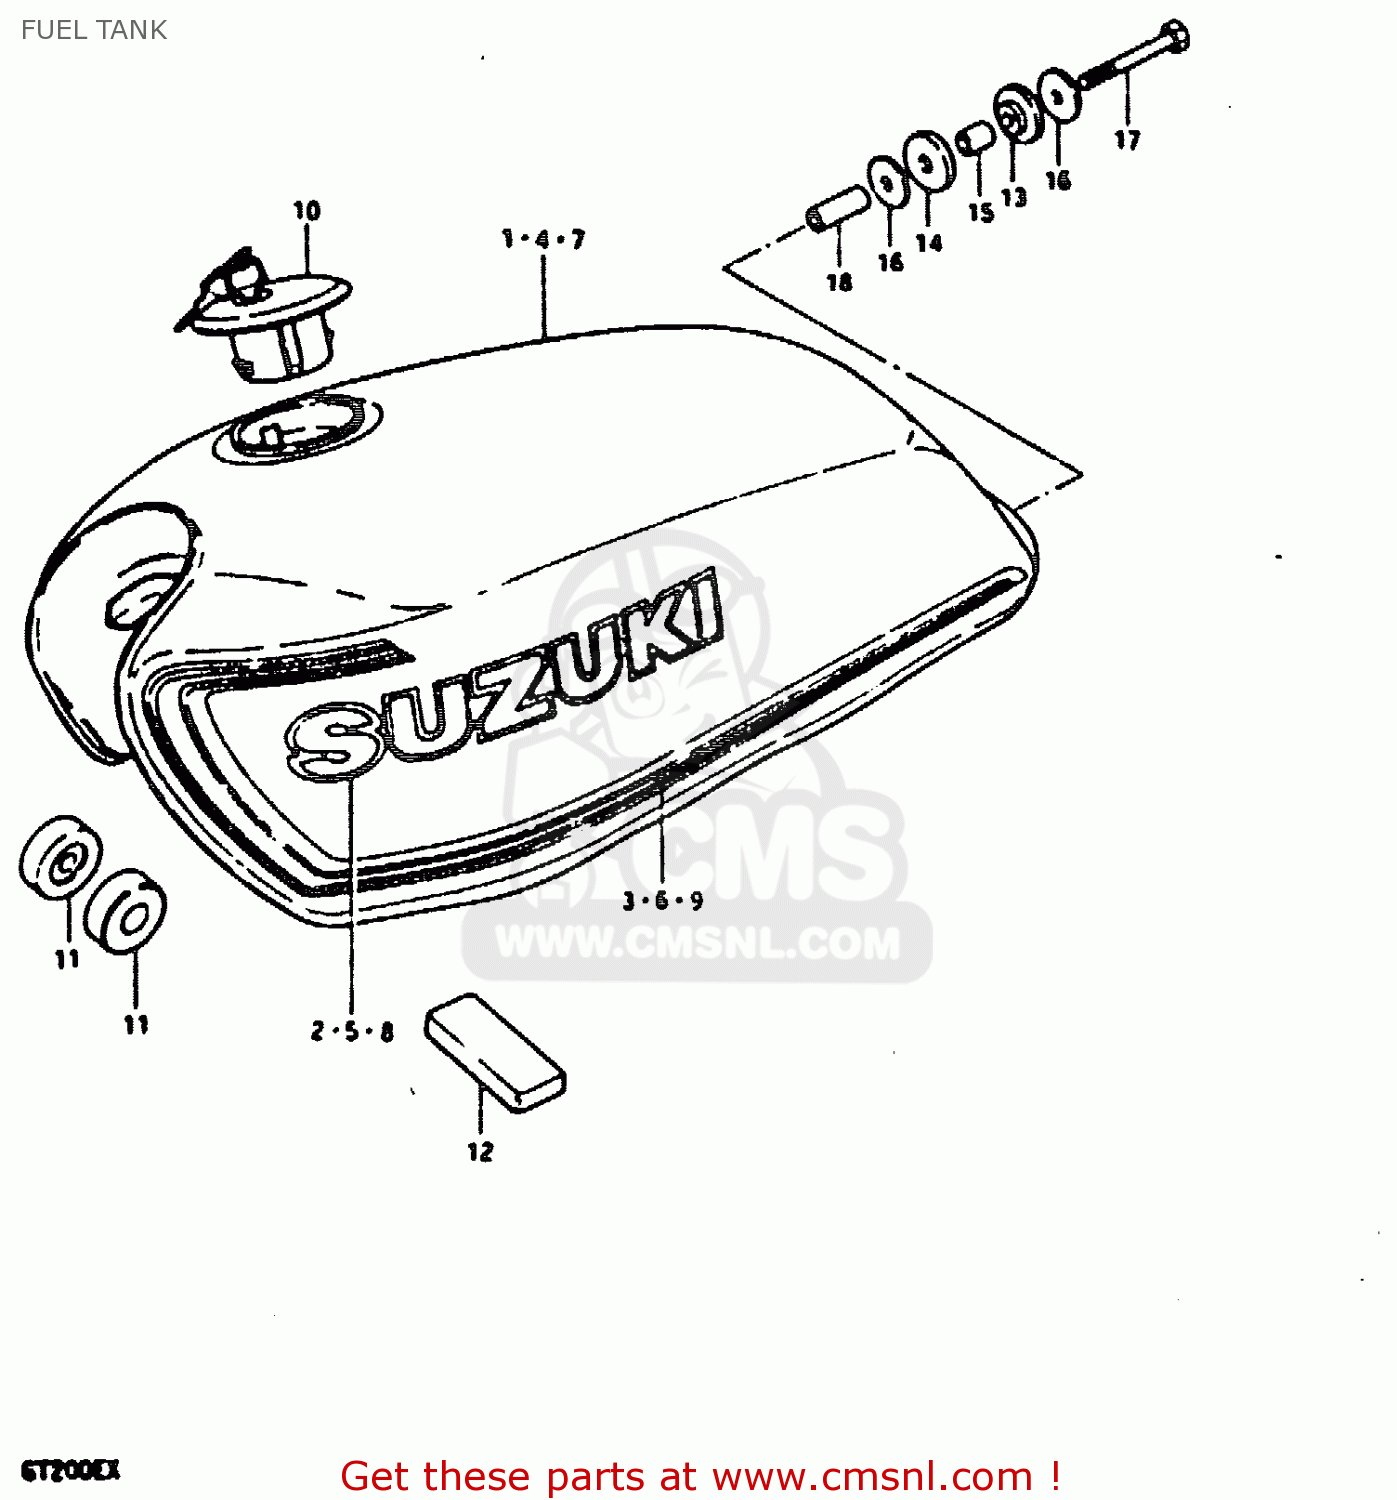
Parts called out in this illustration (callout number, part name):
1	TANK, FUEL (WHITE)
2	EMBLEM
3	TAPE SET
4	TANK, FUEL (BLUE)
5	EMBLEM
6	TAPE SET
7	TANK, FUEL (RED)
8	EMBLEM
9	TAPE SET
10	CAP SET,FUEL TANK
11	CUSHION
12	CUSHION, CENTER
13	CUSHION
14	CUSHION
15	SPACER(8.5X12X19)
16	WASHER (8.5X29X1.6)
17	BOLT
18	SPACER (8.6X13.8X35)
